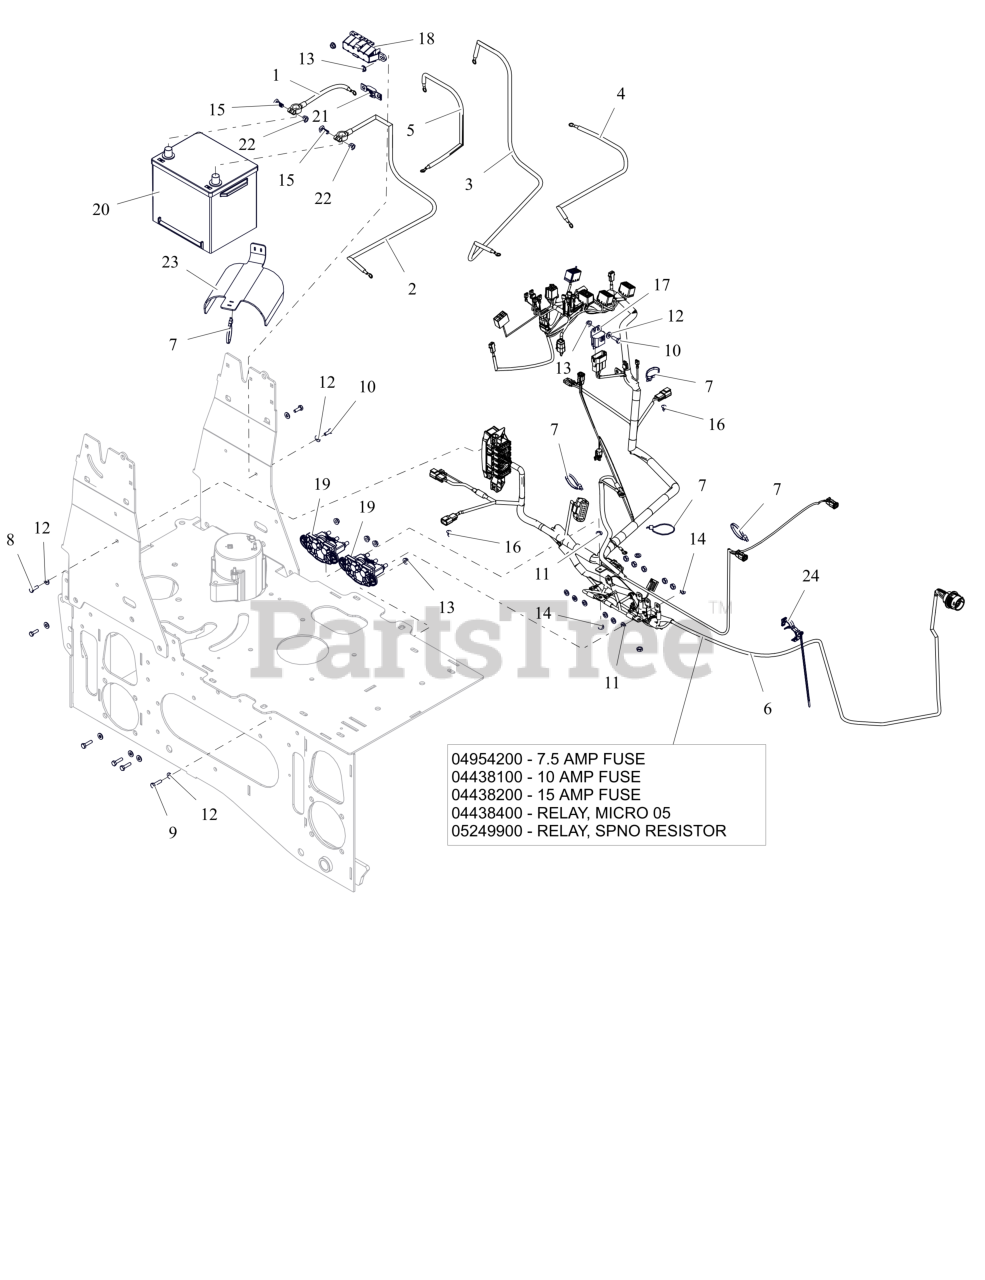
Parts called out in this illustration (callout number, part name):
1	CABLE- BATTERY (POS)
2	CABLE- BATTERY (NEG)
3	CABLE- TRACTOR-ENGINE
4	CABLE- ALT (GROUND)
5	CABLE- ALT (PWR)
6	HARNESS- TRACTOR-MAIN
6	FUSE, 7.5 AMP MINI-ATC
6	FUSE,10 AMP MINI-ATC
6	Fuse, 15 AMP MINI-ATC
6	RELAY,MICRO5 TERML W/RESISTOR
6	RELAY,SPNO,SEALED,ISO280,RESIS
7	TIE WRAP
8	BLT,HEX M6-1X20 G8.8 ZC120
9	BLT,HEX .25-20X1.00 G5 ZCC
10	BLT, HEX .25-20X.75 G5 ZCC
11	WSHR,LK-REG .312X.078 ZCC
12	WSHR,FLT .281X.625X.065 ZCC
13	NUT-LK-CTR-FLG .25-20 ZC120
14	NUT-JAM .312-24 ZCC
15	BOLT- SQ HEAD; BATT TERM
16	RVT-PUSH W/RIBBED SHANK
17	MODULE,INTERLOCK,DELAY, 1801
18	HOLDER- FUSE MEGA (100A)
19	RELAY- ACTUATOR REV POLARITY
20	BATTERY, GROUP 26, 540CCA
21	FUSE- MAIN - 100A MEGA
22	NUT- BATTERY COLLAR NUT
23	SHIELD, RUBBER ALTERNATOR
24	CLIP- HARNESS CABLE TIE
